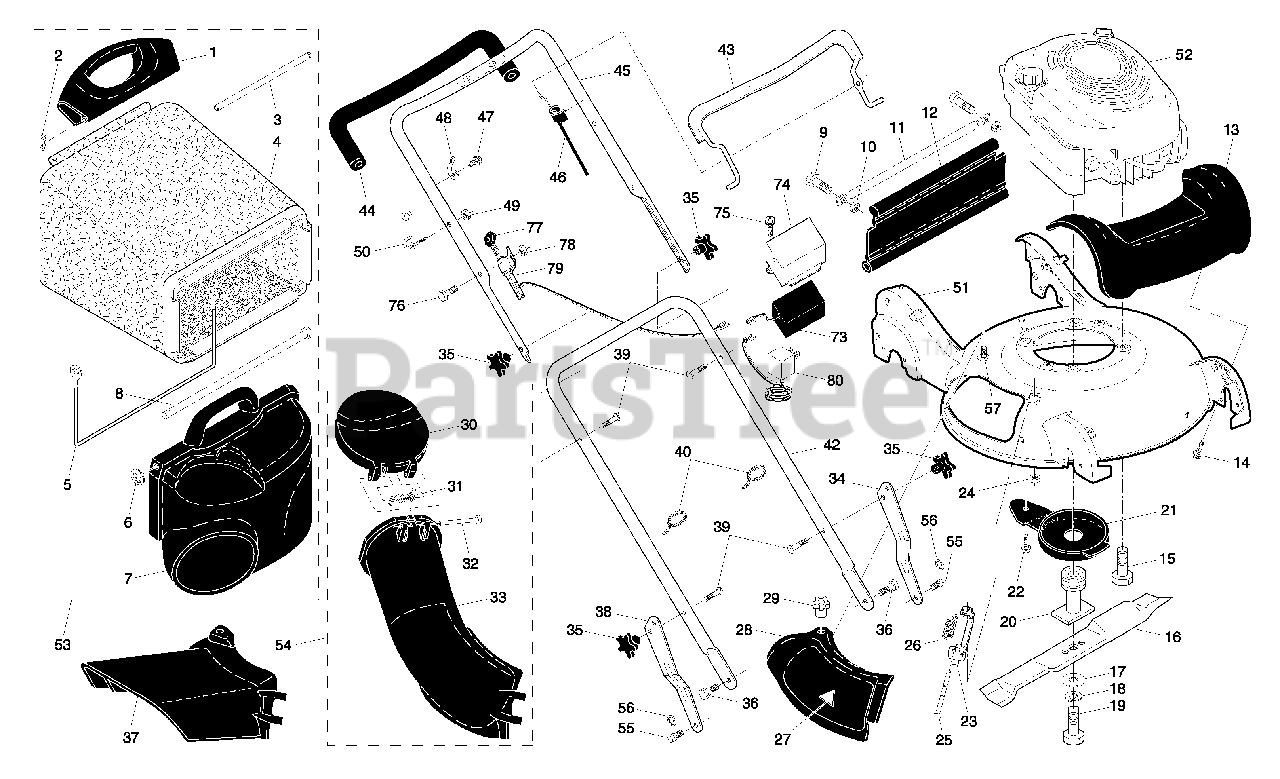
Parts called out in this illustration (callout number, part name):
1	Handle, Grassbag, Rear
2	Hairpin Cotter
3	Rod, Rear Handle, Grassbag
5	Frame, Grassbag
7	Door, Grassbag
8	Rod, Pivot
10	Nut, Hex
11	Tube, Rear Skirt
12	Skirt, Rear
13	Cover, Front
14	Screw, Hex Washer Head
15	Bolt, Engine Mounting
16	Blade, 21"
17	Washer, Hardened
18	Washer, Lock
19	Bolt, Hex Head, Grade 8
20	Adapter, Blade
21	Debris Shield
22	Screw, Hex Head, Serrated
23	Mounting Bracket, Mulcher Door
24	Nut, Hex
25	Rod, Hinge
26	Spring, Mulcher Door
27	Decal, Danger
28	Mulcher Door
30	Door, Discharge Chute
31	Spring, Door, Discharge Chute
32	Rod, Door, Discharge Chute
33	Discharge Chute, Plastic
34	Adjustment Bracket, Lower Handle, LH
35	Knob, Star
36	Bolt, Shoulder
37	Deflector, Discharge
38	Adjustment Bracket, Lower Handle, RH
39	Bolt, Handle
40	Wire Tie
42	Handle Assembly, Lower
43	Bail, Control
44	Grip, Foam
45	Handle Assembly, Upper
46	Cable, Engine Zone Control
48	Bracket, Upstop
49	Nut, Hex 1/4-20
50	Rope Guide
51	Kit, Housing
52	Engine, Briggs & Stratton, Model Number 125K05 (order parts from engine manufacturer)
53	Grassbag Assembly, Complete
54	Discharge Chute Assembly, Complete
55	Stud, Shoulder, T45
56	E-Ring, T45
57	Stud, Threaded 1/4-20 x 5/8
74	Box, Battery
75	Screw, Hex Washer Head #13 x 3/4
76	Screw, Hex Head 1/4-20 x 2-11/64
78	Nut, Hex, Flangelock 1/4-20
79	Control, Electric Start
80	Charger, Battery
